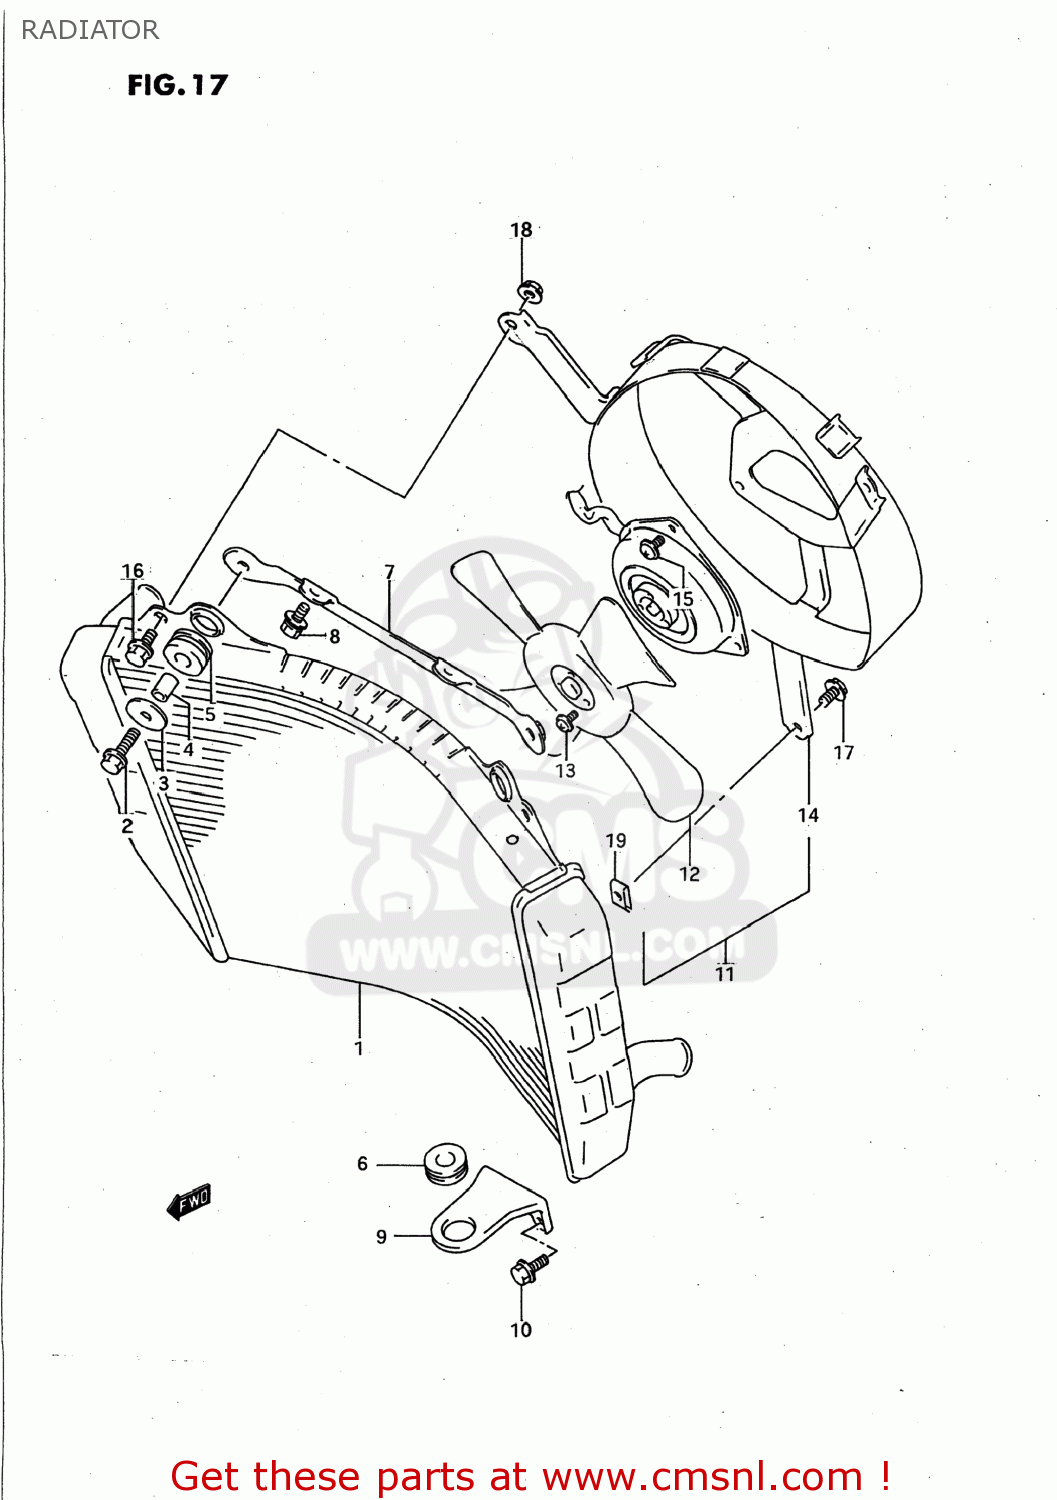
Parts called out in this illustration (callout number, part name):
1	RADIATOR ASSY,WATER
2	BOLT
3	WASHER
4	SPACER(6.5X10.5X12)
5	CUSHION,RADIATOR LWR
6	CUSHION
7	BRACKET COMP,RADIATOR
8	BOLT
9	BRACKET,RADIATOR,LOWER
10	BOLT
11	FAN ASSEMBLY,RADIATOR
12	FAN
13	BOLT
14	SHROUD
15	BOLT
16	BOLT
17	BOLT
18	NUT
19	NUT,RADIATOR COVER
